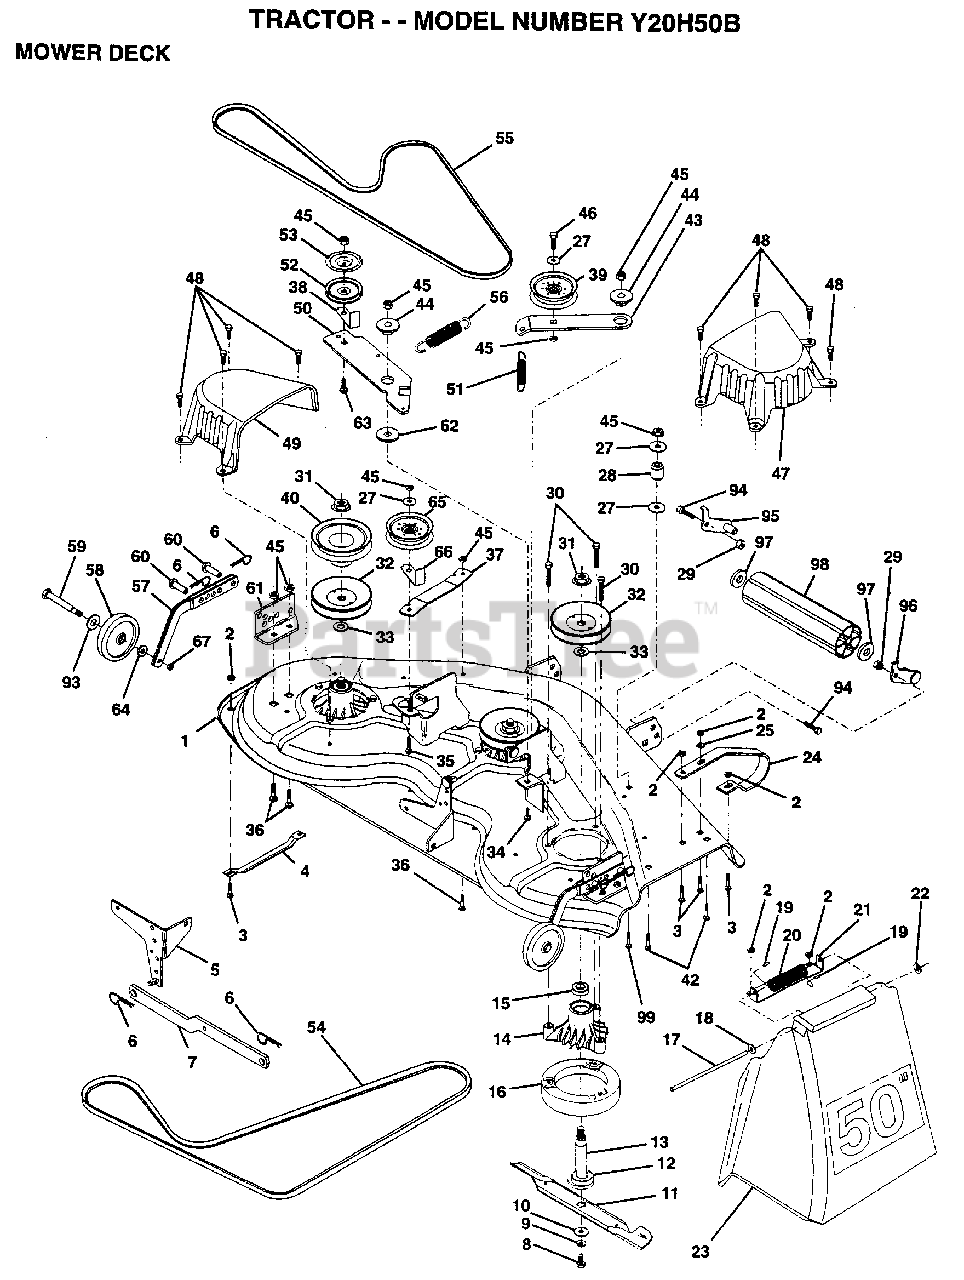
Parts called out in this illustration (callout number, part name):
1	DECK ASM MWR 50VT
4	RUNNER-LH M
5	BRKT.ASM.SW.44/50
8	BLADE BOLT
10	WASHER.HARD.BLADE
11	"BLADE.50"" HD"
12	BEARING.BALL
13	SHAFT.ASM.W/BRNG
14	HOUSING.MAND.44.V
15	BEARING
16	STRIPPER RND MWR
17	ROD-HINGE T
18	WASHER
19	CAP-SLEEV(107627)
20	SPRING.(150051)
21	BRKT DEFLECTOR
22	NUT PUSH M
23	DEFLECTOR
24	"RUNNER RH 50"" DK"
25	WASHER M
27	WASHER
29	NUT
33	WASHER
34	BOLT.3/8-14X1.25
35	BOLT
36	BOLT D
37	STIFFENER.ARM.IDL
39	FLAT IDLER PULLEY
40	"PULLEY.DRIVEN.44"""
42	BOLT
43	"ARM.IDLER.SEC.44"""
47	"COVER.MAND.RH.44"""
48	SCREW.1/4-20X5/8
49	COVER.MANDREL.LH
50	ARM.IDLER.PRIMARY
51	"SPRING.SEC.44""VEN"
52	PULLEY.IDLER.VGRO
53	SHIELD.IDLER.44.V
54	BELT V PRIM 50
55	BELT-V.SEC.46.KEL
56	SPRING.EXT.DECK.
57	BAR.ASM.GUAGE.WHL
58	WHEEL.GAGE.BLK.PL
59	BOLT M
60	PIN.CLEVIS
61	BRACKET.GUAGE.WHL
62	HARDENED WASHER
63	BOLT.3/8-16X1.50
64	WASHER
65	IDLER-FLAT T
67	LOCKNUT
93	WASHER
94	BOLT
97	WASHER
99	BOLT
